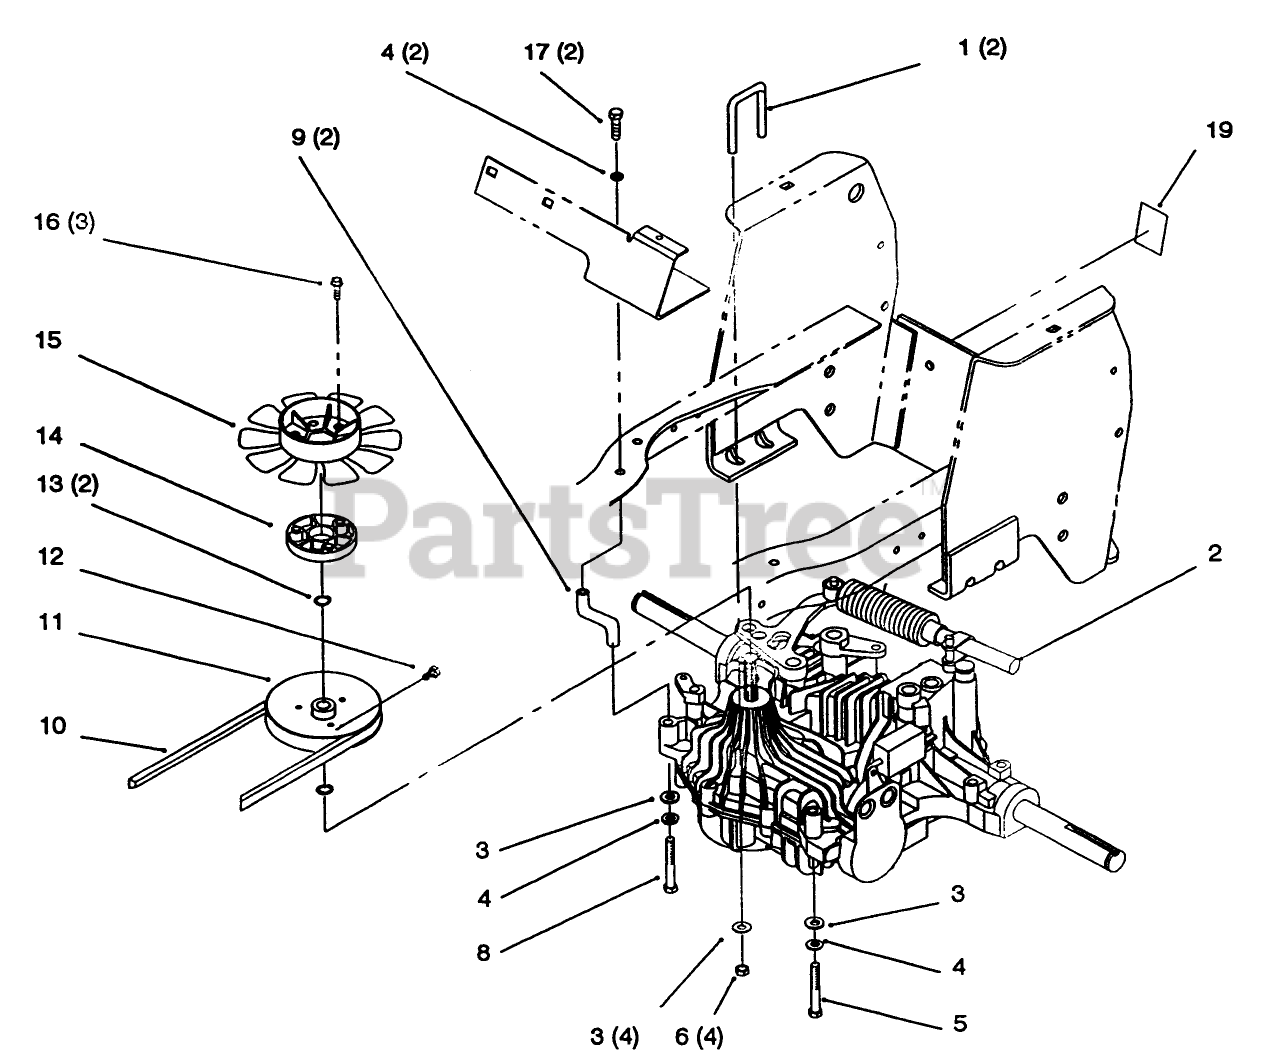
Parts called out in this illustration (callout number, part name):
1	U-BOLT
3	WASHER-PLAIN
4	WASHER-LOCK
5	SCREW-HH
6	NUT-LOCK, NI
8	SCREW-HH
9	STRAP - TORQUE HYDRO
11	PULLEY-HYDRO TRANS
12	SCREW-HSH
13	RING-RETAINING
14	SPACER - FAN
15	FAN - HYDRO
16	SCREW-HWHTF
17	SCREW-HH
19	DECAL-VALVE, HYDRO
19	DECAL-BYPASS VALVE
